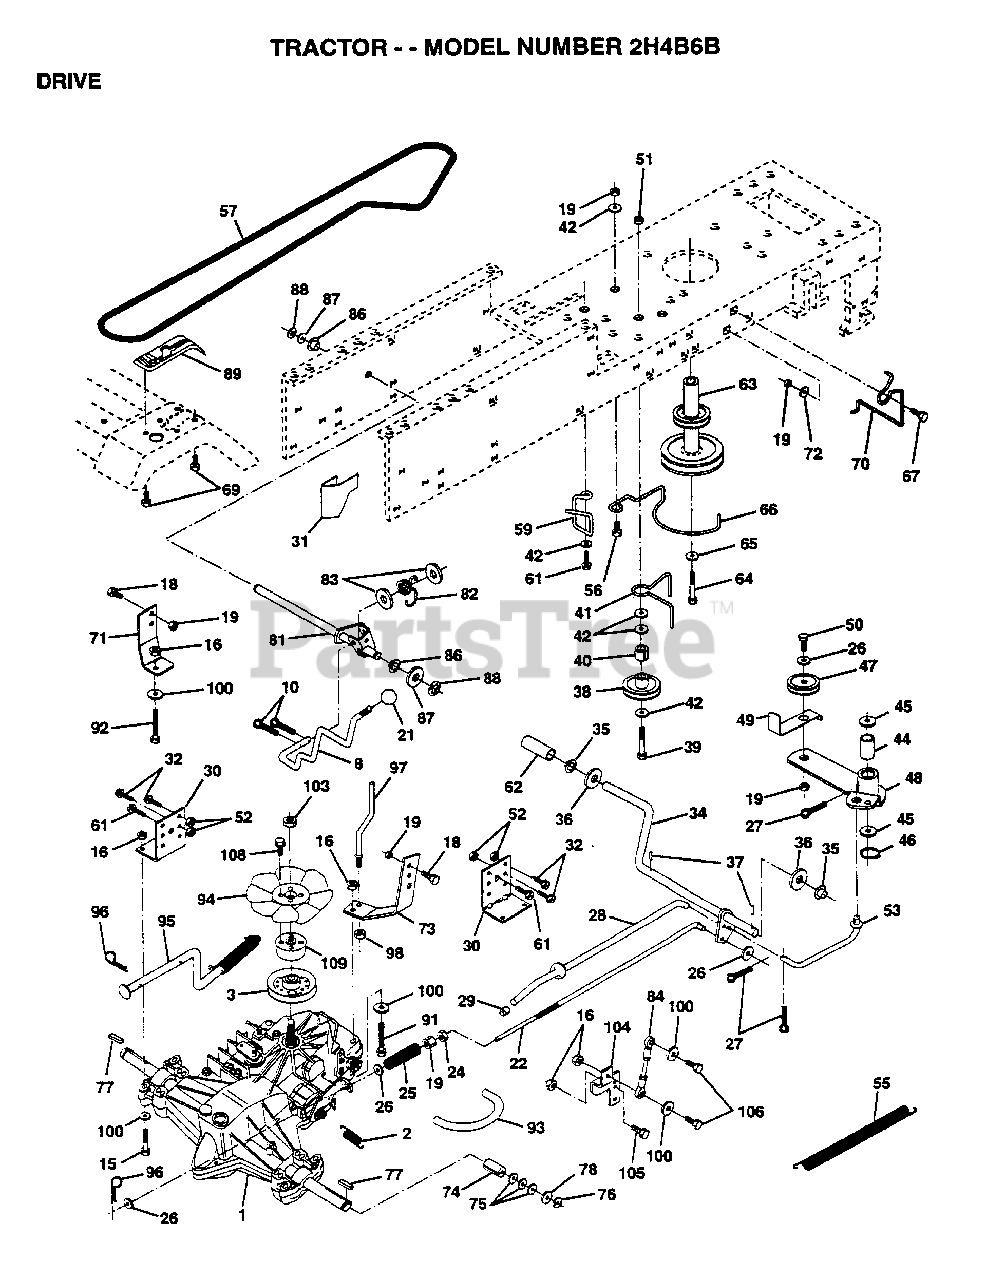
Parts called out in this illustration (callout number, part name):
1	TRANSAXLE HYD 0319-0500
2	SPRING RET BRAKE
3	PULLEY.4.20.HYDRO
8	ROD SHIFT FEND LT
10	PIN COTTER 1/8
15	BOLT HEX
16	NUT
18	BOLT
19	NUT
21	KNOB T (1/2-HOLE)
22	ROD.BRAKE.HYDRO.
24	NUT
25	SPRING ROD LT
26	WASHER
27	COTTER PIN
28	ROD.BRAKE.PARK.LT
29	PLUNGER CAP T
30	TRANSAXLE MTG BKT
31	"KEEPER,BELT LH T"
32	BOLT
36	WASHER LT
38	PULLEY.IDLER.FLAT
39	BOLT
40	SPACER T
41	BELT KEEPER LT
42	WASHER
44	"LY, BEARING"
45	WASHER LT
46	KLIP RING
48	ARM IDLER
49	RETAIN BELT
53	"LINK, CLUTCH T"
55	"SPRING, RETURN LT"
57	BELT-V.HYDR.84.61
59	KEEPER BELT CNTSP
61	SCREW
62	PEDAL COVER T
63	PULLEY.ENGINE
64	BOLT
65	NYLON BEARING
65	LOCKWASHER
66	KEEPER.BELT.ENG.L
67	BOLT
69	SCREW HEXWSH H-L
70	KEEPER BELT ENG
71	STRAP.TORQ.LH.HYD
72	WASHER
73	STRAP.TORQ.RH.HYD
74	SPACER SPLIT
75	WASHER
76	E-RING LT
77	SQUARE KEY
78	WASHER
81	SHAFT.CROSS.HYD
82	"SPRING,TORSION"
83	WASHER
84	ROD.TIE.BALL.HYD.
86	BUSHING
87	WASHER D
88	KLIP RING
92	HEX BOLT
93	"LINE FUEL HYD 4"""
94	"FAN 7"" HYDRO"
96	RETAINER M
97	KEEPER.BELT.RH.HY
98	NUT
100	WASHER M
104	ARM.CONTROL.PUMP
105	SCREW CAP 5/16-18
106	BOLT
108	SCREW.HXHD.10-20
109	ADAPTOR.FAN.HYDRO
